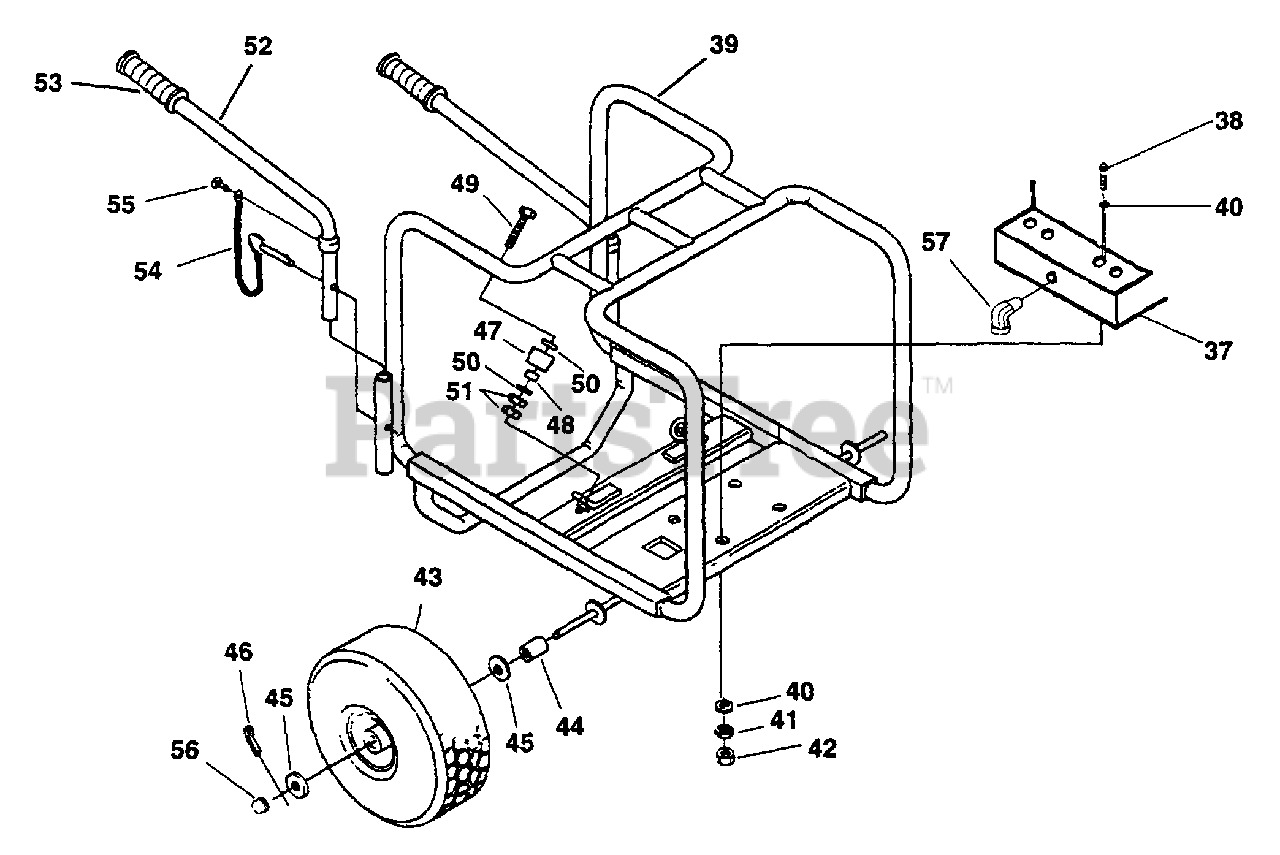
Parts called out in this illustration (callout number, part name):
37	ENGINE, V-TWIN, 16 HP
38	CAP HEX HD SCREW (5/16-18 X 2.75)
39	ROLL CAGE
40	FLAT WASHER (5/16)
41	LOCK WASHER (5/16)
42	HEX NUT (5/16-18)
43	WHEEL & TIRE
45	FLAT WASHER
46	COTTER PIN (DIA.156 x 1.50)
47	RUBBER FOOT
49	HEX HD SCREW (5/16-18 X 2.75)
50	FLAT WASHER (5/16)
51	HEX NUT (5/16-18)
53	GRIP, HANDLE
54	HITCH PIN & LANYARD
55	TRUSS HD SCREW (8-32 X .38)
56	HUB CAP
57	3/8 NPT STREET ELBOW
